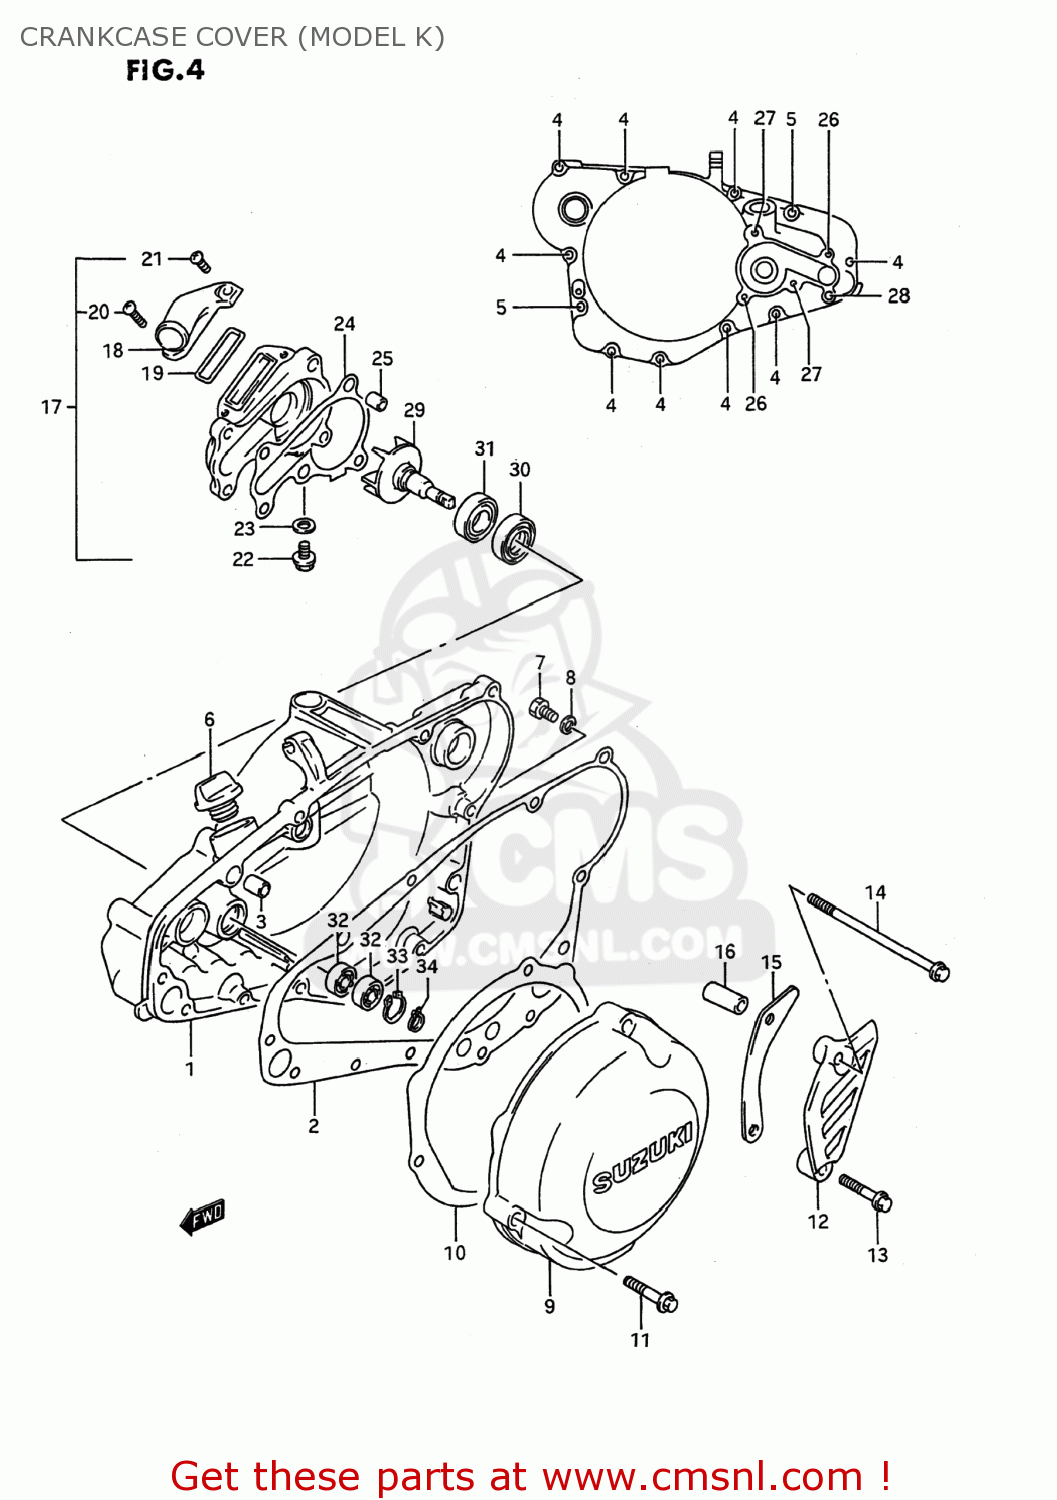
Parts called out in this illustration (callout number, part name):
1	COVER,CLUTCH
2	GASKET,CLUTCH COVER (NAS)
3	PIN
4	BOLT
5	BOLT
6	PLUG SET
7	SCREW(6X10)
8	GASKET(6.2X11X1).2 (NAS)
9	COVER,MAGNETO
10	GASKET,MAGNETO COVER (NAS)
11	BOLT
12	COVER,SPROCKET
13	BOLT
14	BOLT 6X95
15	PLATE,FR CHAIN GUIDE(13T)
16	SPACER(6.5X10.5X25)
17	CASE ASSY,WATER PUMP
18	CONNECTOR
19	O RING
20	SCREW
21	SCREW
22	BOLT,BLEEDER
23	GASKET (NAS)
24	GASKET,WATER PUMP CASE (NAS)
25	PIN
26	BOLT
27	BOLT
28	BOLT
29	IMPELLER,WATER PUMP
30	SEAL,OIL(12X24X3.6)
31	SEAL,OIL(12X24X6.4)
32	BEARING
33	CIRCLIP
34	CIRCLIP
